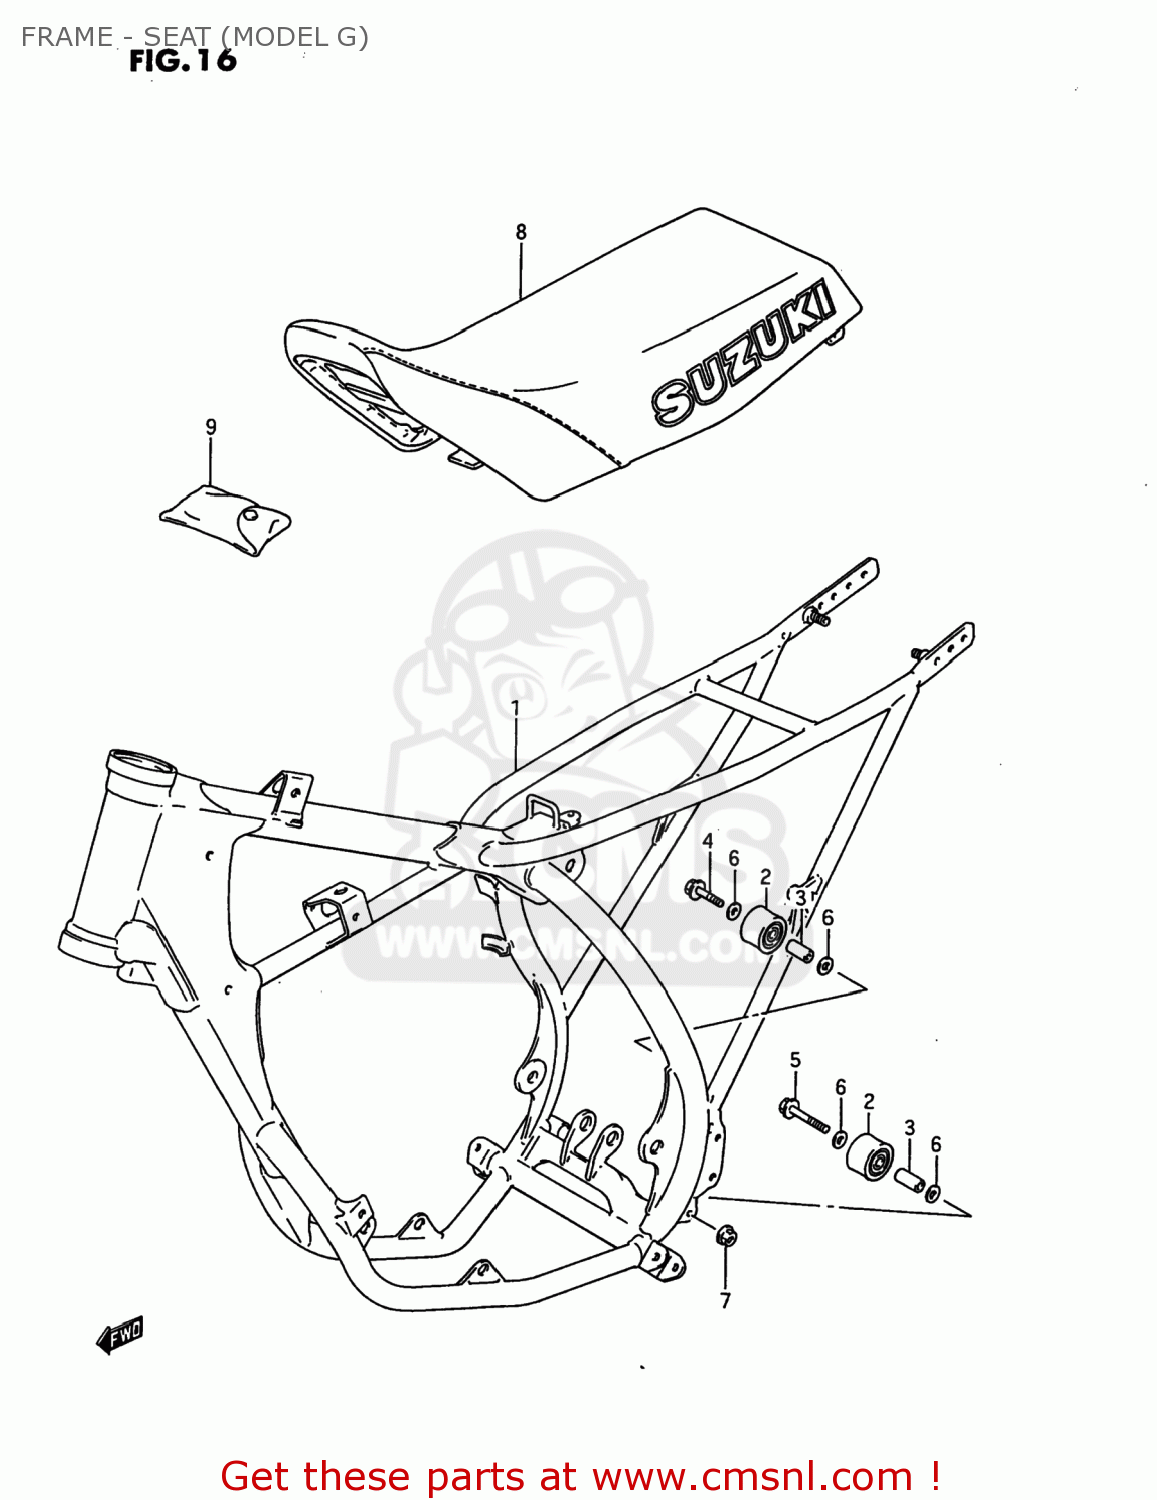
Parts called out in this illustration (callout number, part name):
1	FRAME
2	ROLLER,CHAIN CONTROL
3	SPACER(8.6X12X25.5)
4	BOLT(8X41)
5	BOLT(8X45)
6	WASHER
7	NUT
8	SEAT ASSEMBLY
9	TOOL SET
